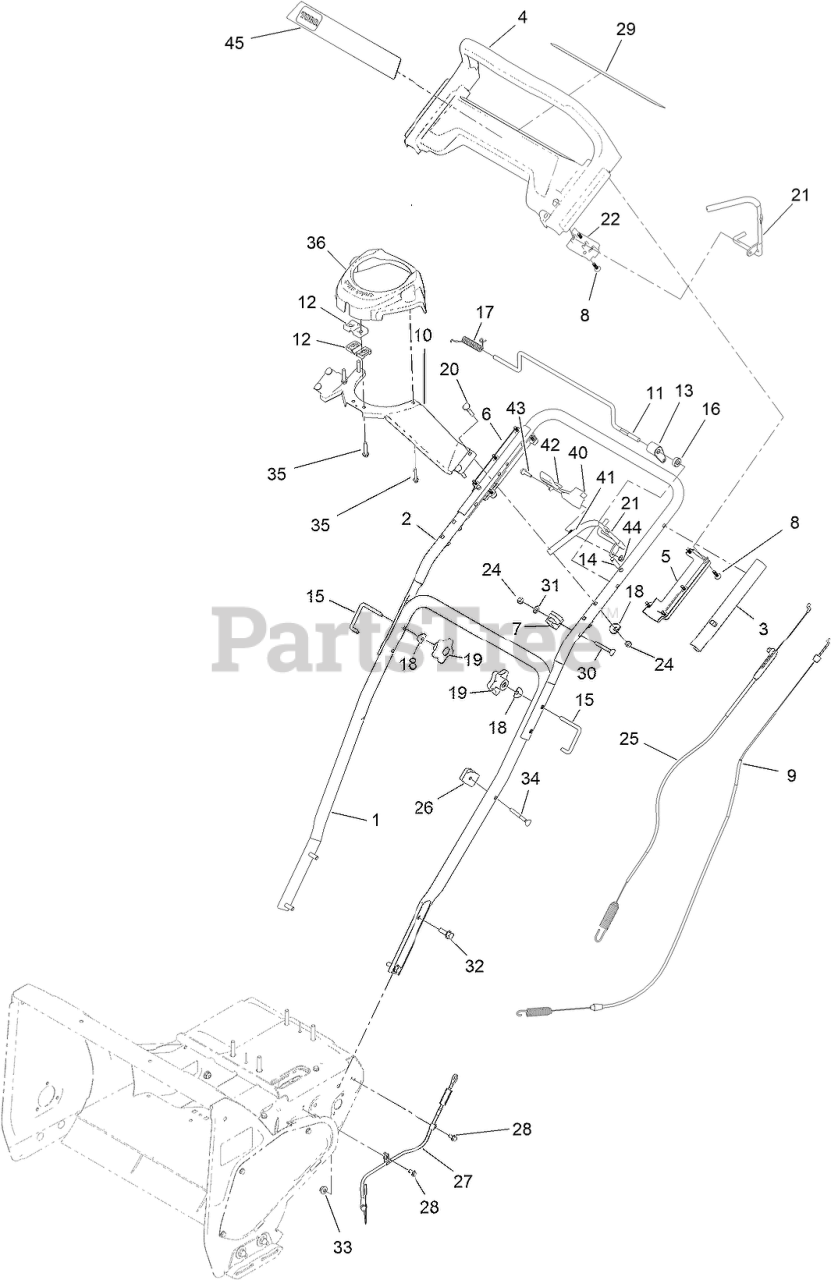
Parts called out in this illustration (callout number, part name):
1	HANDLE-LOWER
2	HANDLE-UPPER
3	SLEEVE HANDLE
4	HANDLE PP ASM W/ DECAL
5	HANDLE-BOTTOM, LH
6	HANDLE-BOTTOM, RH
7	CABLE-GUIDE
9	CABLE-TRANSMISSION
10	BRACKET-CHUTE, CONTROL
11	BAR-CONTROL, TRACTION
12	SUPPORT-ROD
13	LEVER-TRACTION
14	PIN-DOWEL
15	LOCK-HANDLE
16	SPACER
17	SPRING-TORSION
18	WASHER-CUP
19	KNOB-HANDLE
20	SCREW-HANDLE
21	ASM-BAIL
22	BAIL-MOUNT
24	NUT-HEX
25	CABLE-ROTOR, UPPER
26	ANCHOR-CABLE, UPPER
27	CABLE-ROTOR, LOWER
28	SCREW-HWH
29	DECAL-CONTROL, PANEL
30	BOLT-CARR
31	WASHER-FLAT
32	SCREW-HHF
33	NUT-HF
34	SCREW-HANDLE
35	SCREW-PLASTIC,HWH
36	COVER-TOP
41	SPRING-TORSION
43	SCREW-SHOULDER
44	NUT-HEX FLANGE
45	DECAL-DISPLAY
